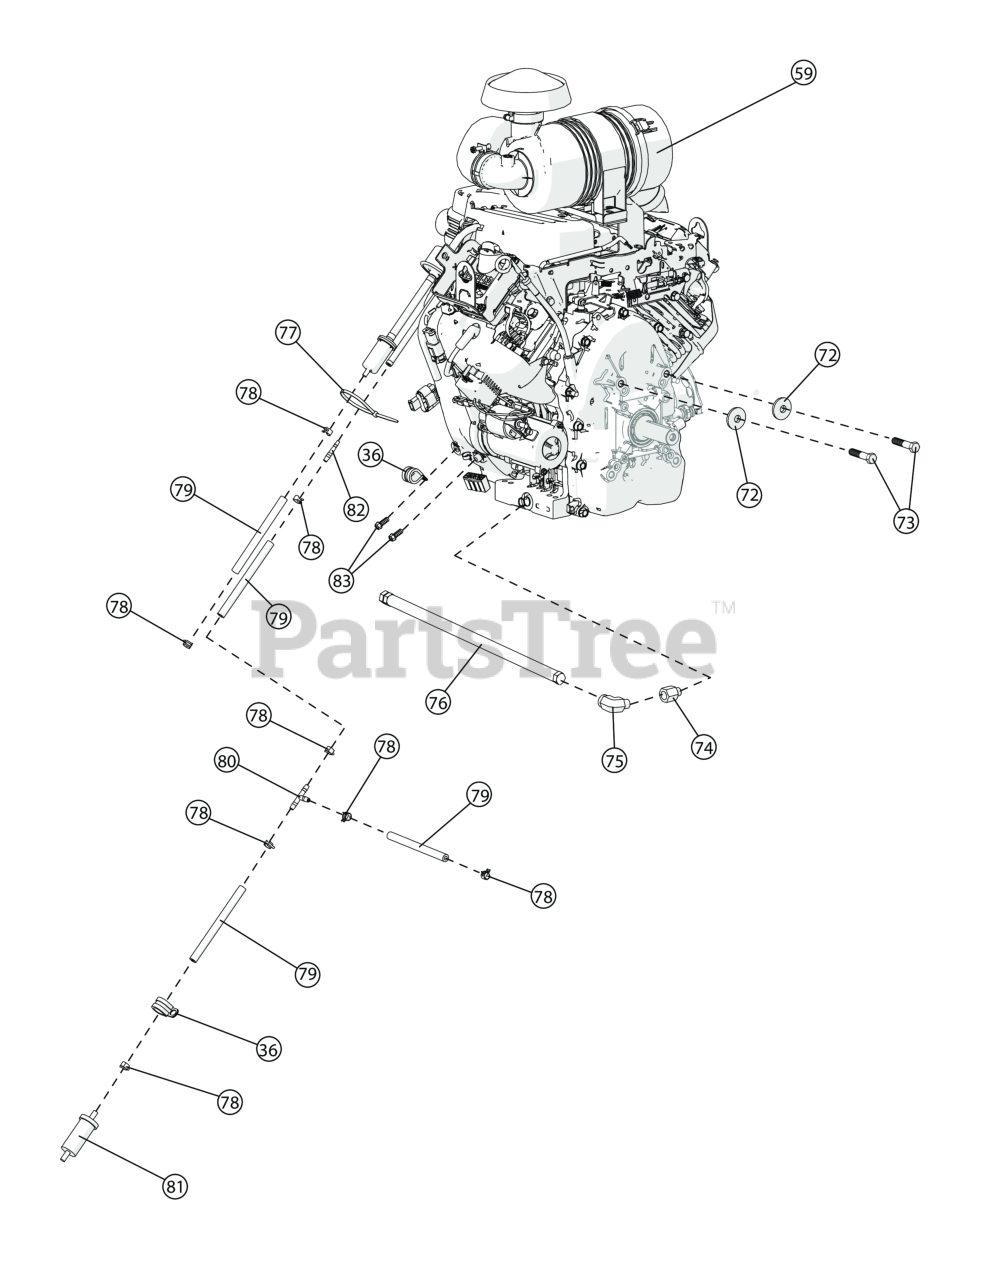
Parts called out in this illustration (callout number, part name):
36	CLAMP ROUTING FUEL LINE
59	ENGINE 37HP EFI HORZ. SHAFT B&S
72	WSHR-STL,BLV, .450"X1.500"X.172" MZ
73	SCREWCAP 7/16"-14 X 2" GR.5 W/PATCH LOCK
74	METRIC ADAPTER, M14-1.5" TO 3/8 NPTF
75	ADAPTER, 90° ST ELBW 3/8M-3/8F NPT
76	HOSE, 20" OIL DRAIN - .375- 18 NPTF
78	CLAMP, FUEL LINE 0.50"
79	FUEL LINE 1/4" ID X 6"
80	1/4" X 1/4" X 1/4" BARB TEE FITTING
81	FUEL FILTER BRIGGS
82	1/4" TO 3/16" HOSE BARB REDUCER SPLICER
83	SCREW SM 1/4"X3/4" TYPE A HX WF
